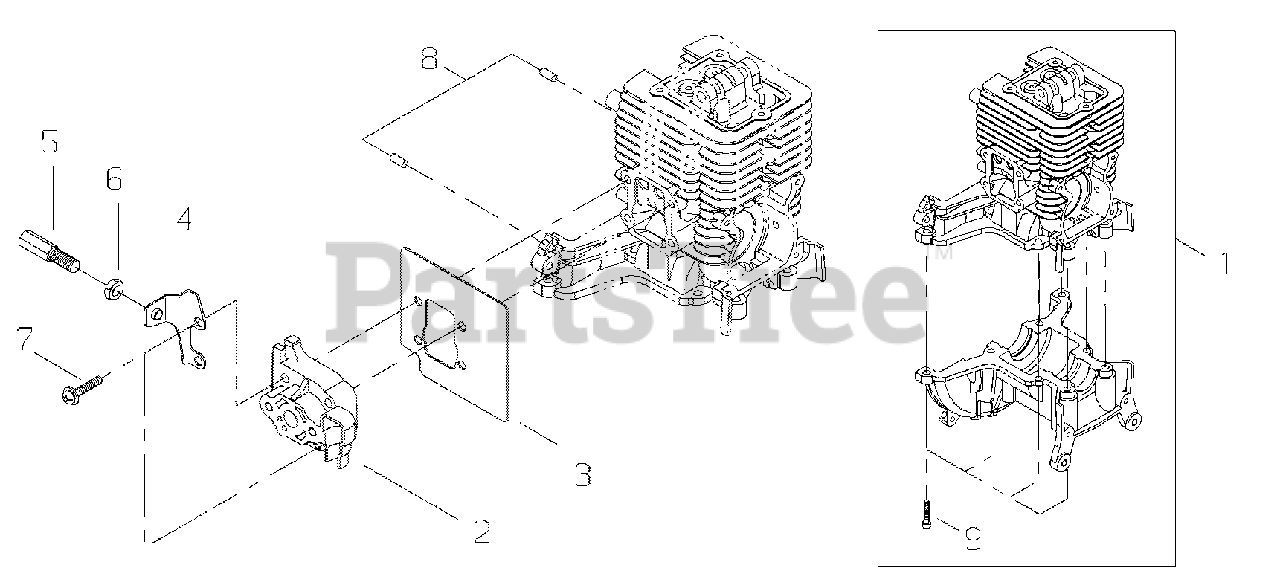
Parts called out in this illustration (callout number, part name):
1	CYLINDER BLOCK SET
2	VALVE, REED
3	DEFLECTOR, HEAT
4	BRACKET, THROTTLE CABLE
5	NUT, CABLE ADJUST
6	LOCKNUT - 6
7	SCREW - 5X25
8	PIN - LOCATING
9	SCREW - 5X16
